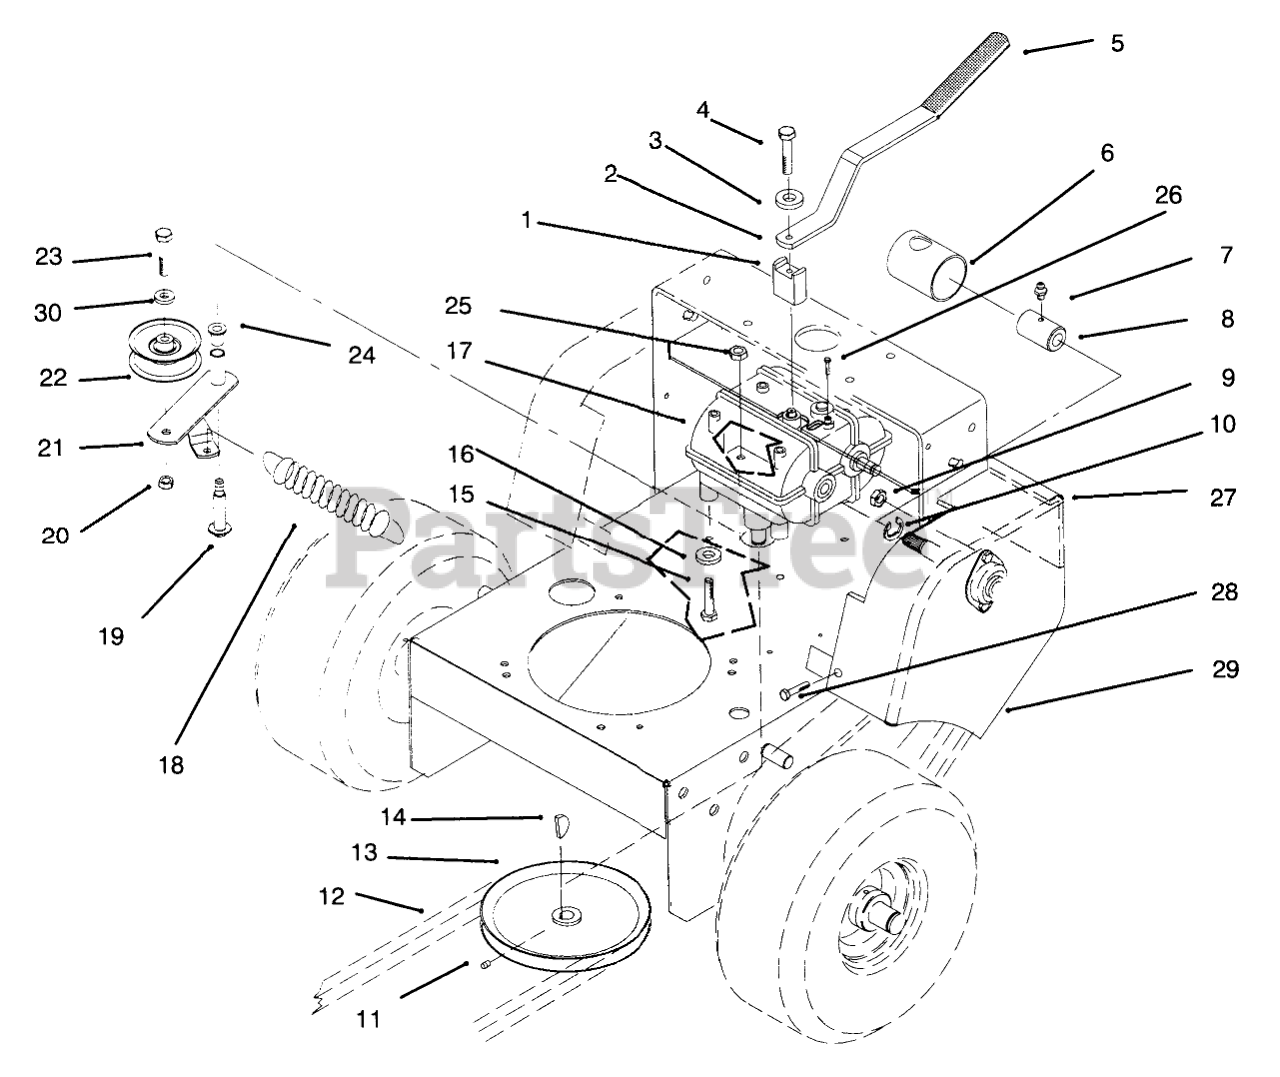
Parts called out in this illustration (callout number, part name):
1	MOUNT-LEVER, SHIFT
2	Lever-Shift
3	SPACER
4	SCREW-HH
6	GUARD-COUPLER
7	FITTING-GREASE
8	COUPLER
9	NUT-LOCK, NI
10	RING-SNAP, EXTERNAL
11	SCREW-SET
12	BELT V
13	PULLEY-DRIVEN
15	SCREW-HH
16	WASHER-LOCK
17	TRANSMISSION
18	SPRING
19	BOLT-WHEEL
20	NUT-LOCK, NI
21	Lever-Idler (Incl. Ref.#24)
22	PULLEY
23	SCREW-HH
24	BUSHING-FLANGE
25	NUT-LOCK
26	SCREW-HWHTF
27	Guard-Shaft Trans.
28	SCREW
29	GUARD - LH BELT
30	WASHER-FLAT
